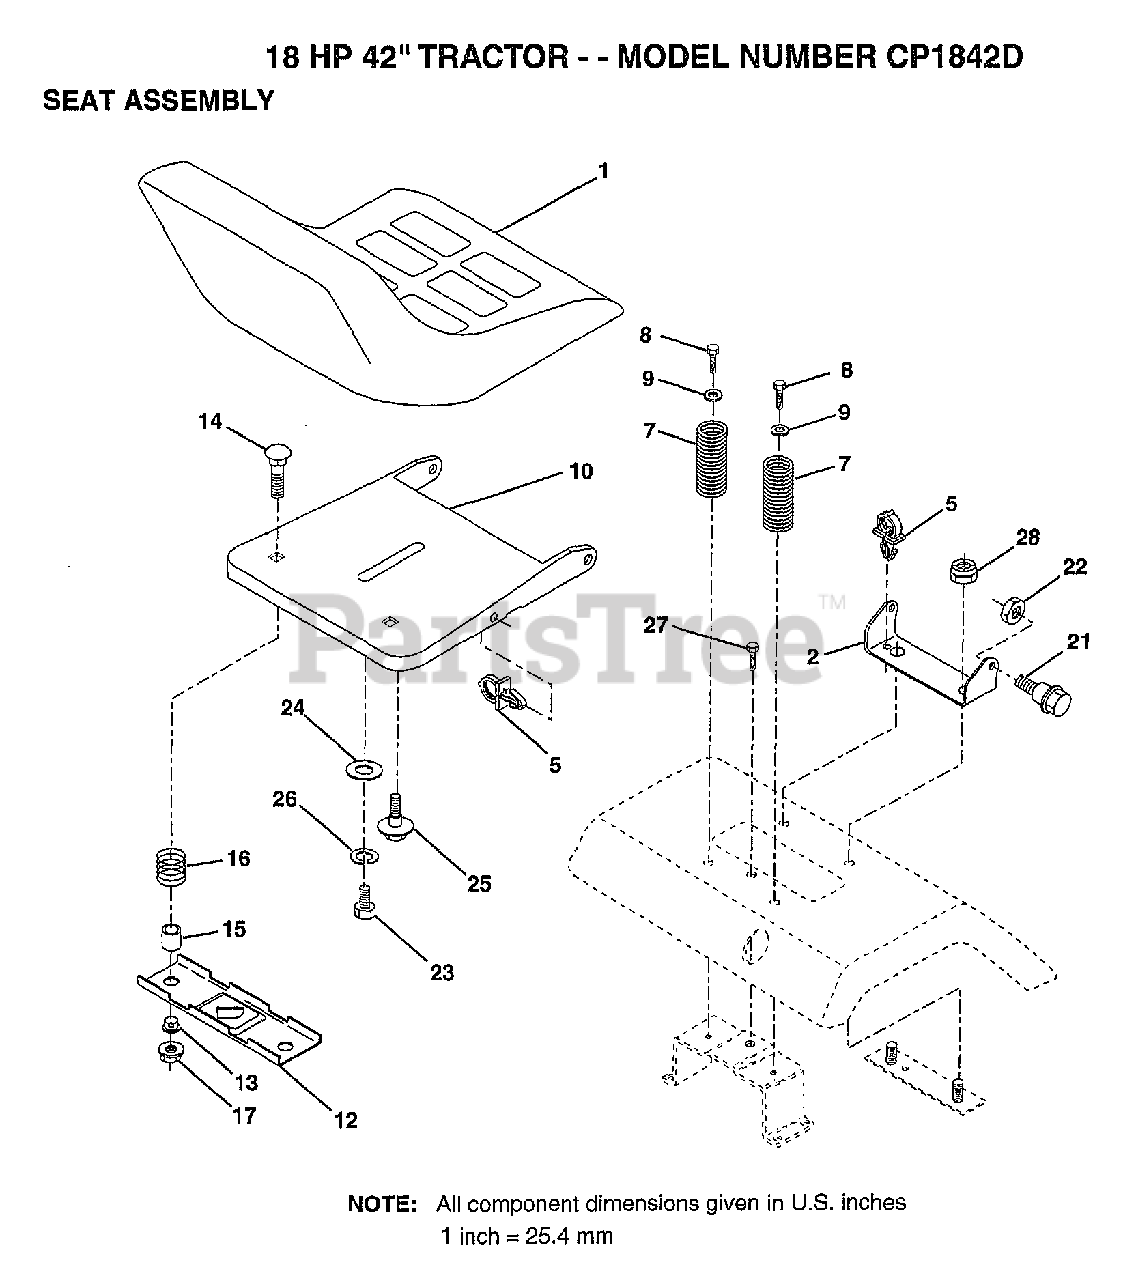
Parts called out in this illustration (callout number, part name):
2	BRACKET PVT SEAT
5	CLIP PUSH - IN
7	SPRING COMPRESSIO
8	SCREW LT
9	WASHER
12	BRKT SWITCH
13	BUSHING
15	SPACER SPLIT
16	SPRING COMPRESSED
21	BOLT.SHLD.5/16-18
23	BOLT
24	WASHER
25	"BOLT,SHOULDER"
26	LOCKWASHER
27	SCREW LT
